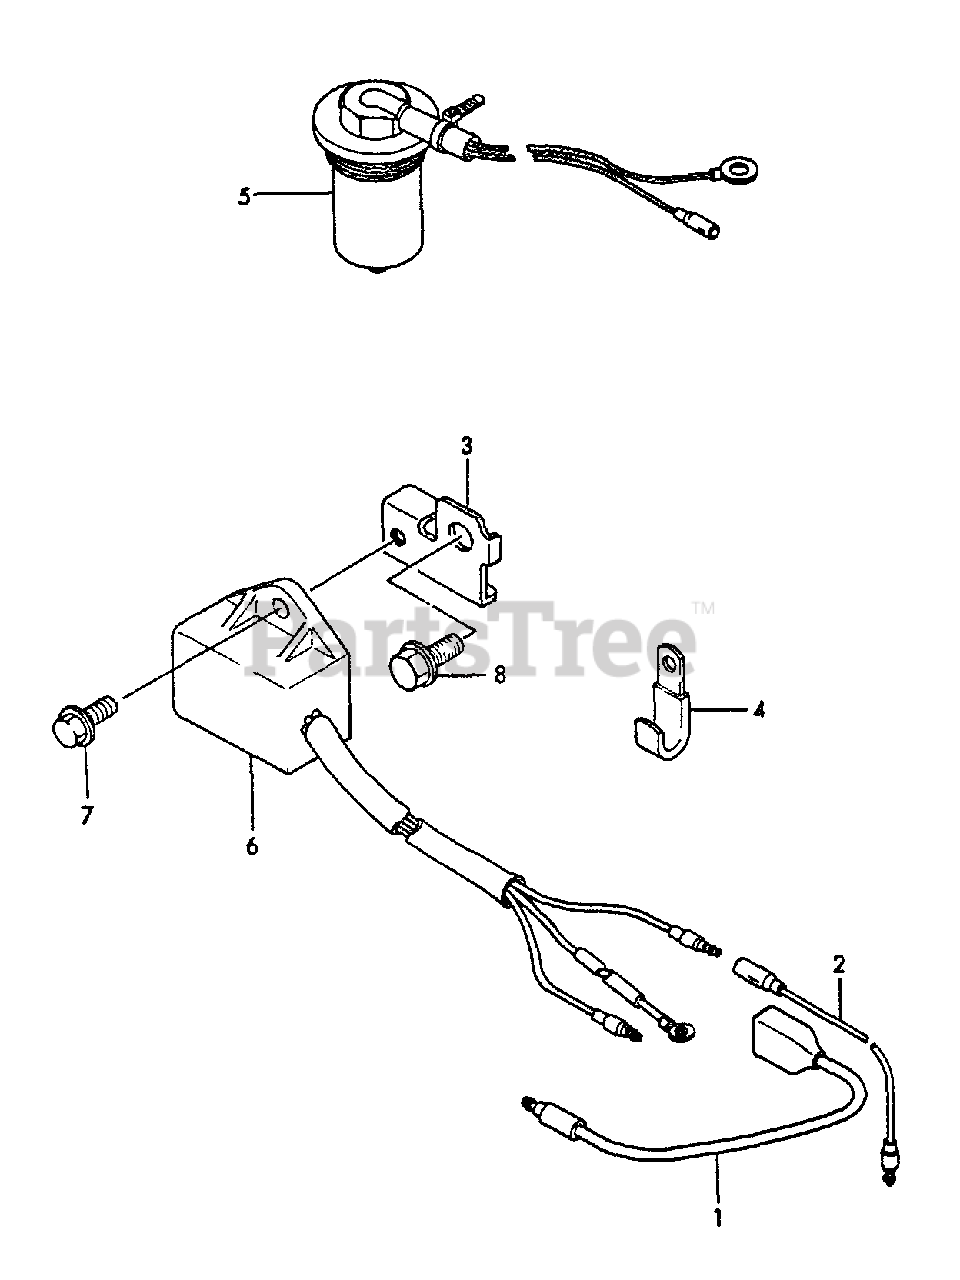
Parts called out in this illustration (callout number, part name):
1	WIRE
2	WIRE
3	STAY, SENSOR UNIT
4	CLAMP
5	SENSOR UNIT
6	SENSOR, OIL LEVEL
7	BOLT - 6×12 -- PLATED
8	BOLT - 8×14 -- PLATED
